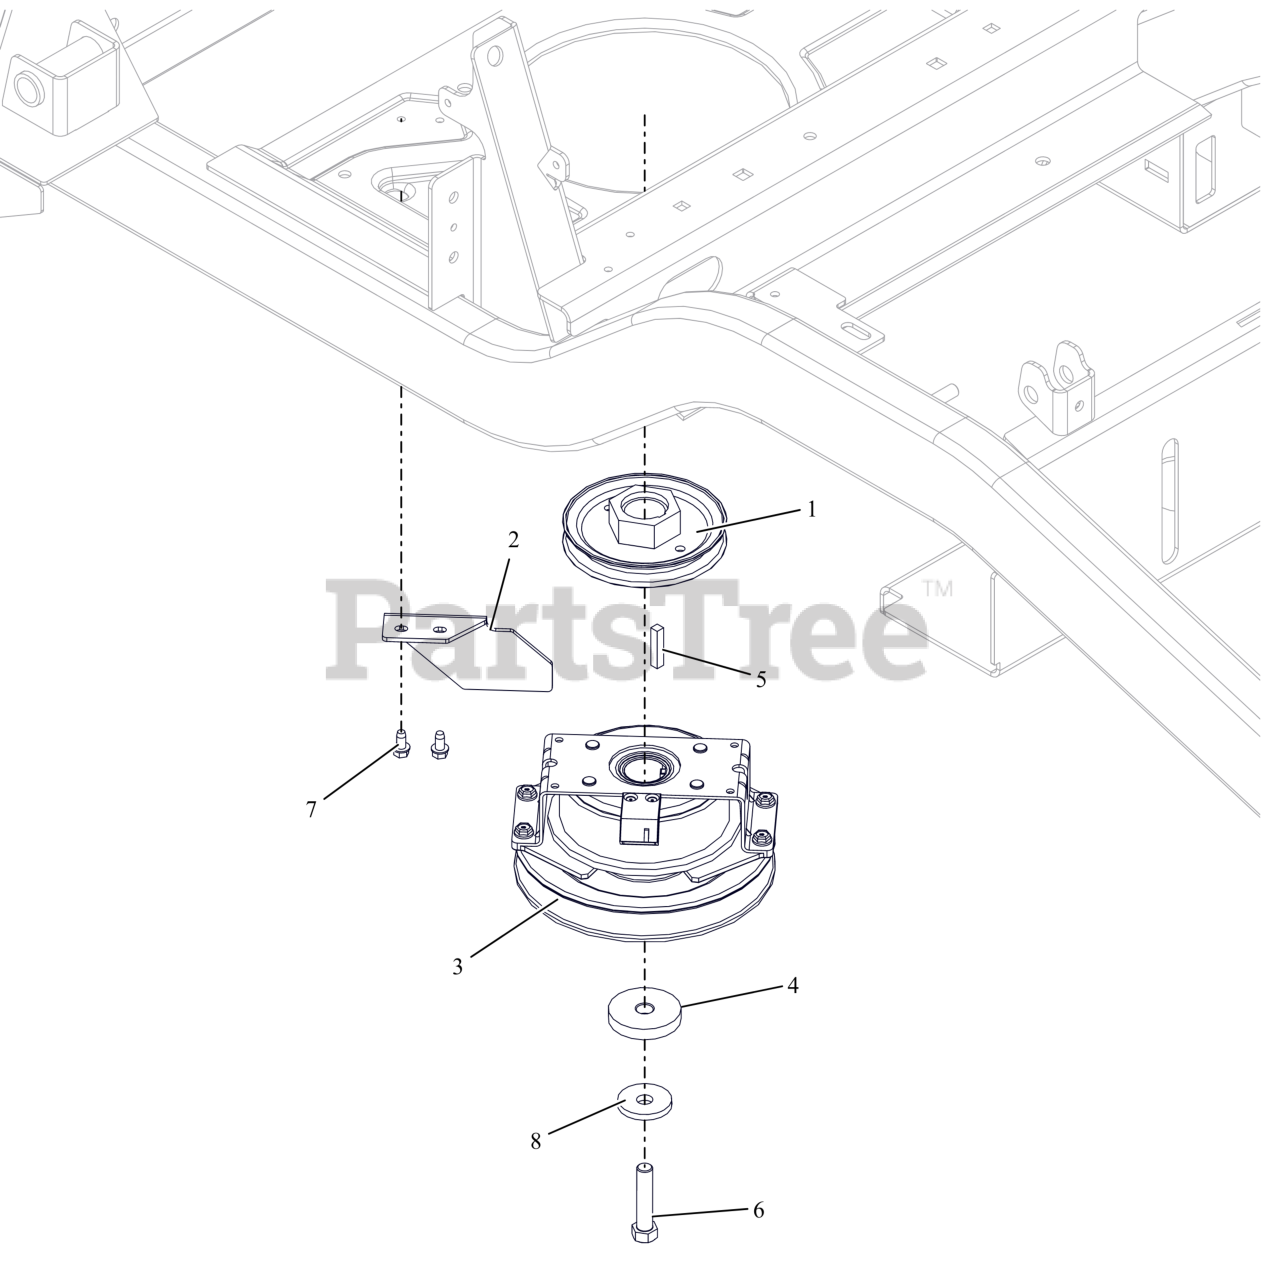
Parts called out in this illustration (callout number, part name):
1	WLDMT,PULLEY-4.50ODX1.127
2	BRKT, CLUTCH STOP HD
3	CLUTCH, OGURA DBLS SPRG 1.13"
4	SPACER, .474/.459X2.00X.350
5	KEY-SQ .25 X 1.25 X .25 SAE
6	BLT, HEX .44-20X2.00 G8 ZCC NT
7	SCR-TAP .25-20X.50 HWH ZCC
8	WASHER, 7/16" SPRING DISK
